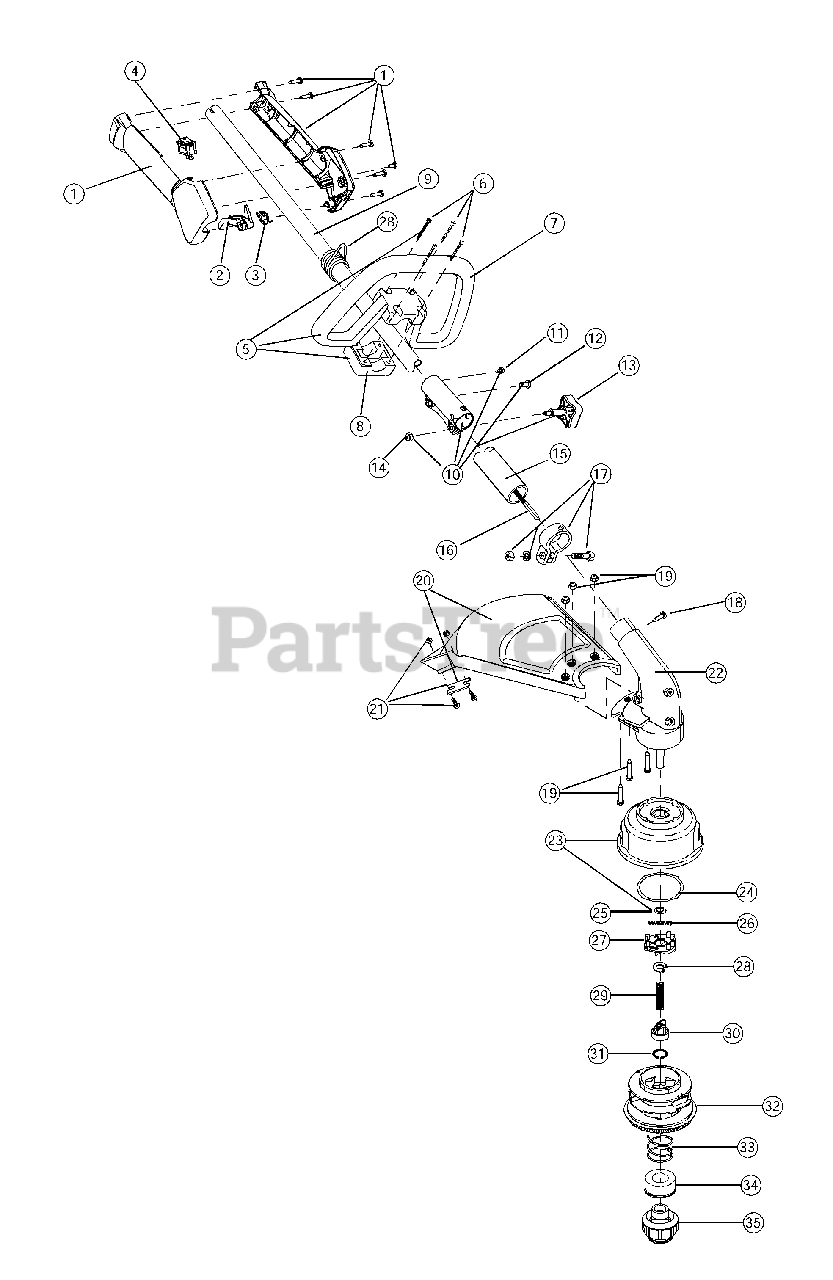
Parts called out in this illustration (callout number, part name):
1	Throttle Housing and Trigger Assembly
2	Throttle Trigger
3	Throttle Trigger Spring
4	Switch Assembly
5	Deluxe D-Handle Assembly
6	Handle Mount Hardware
7	Deluxe D-Handle
8	Bottom Clamp
9	Upper Drive Shaft Housing Assembly
10	EZ-Link (TM) Coupler
13	Adjustment Knob
14	Knob Retaining Nut
15	Lower Drive Shaft Housing Assembly
16	Lower Flexible Drive Shaft
17	Lower Clamp Assembly
18	Anti-Rotation Screw
19	Shield Mounting Hardware
20	Shield and Blade Assembly
21	Blade Assembly
22	Gearbox Assembly
23	Outer Spool & Eyelet Assembly
24	Retaining Ring
25	Thrust Washer
26	Small Spring
32	Inner Reel
33	Large Spring
35	Bump Head Knob Assembly
